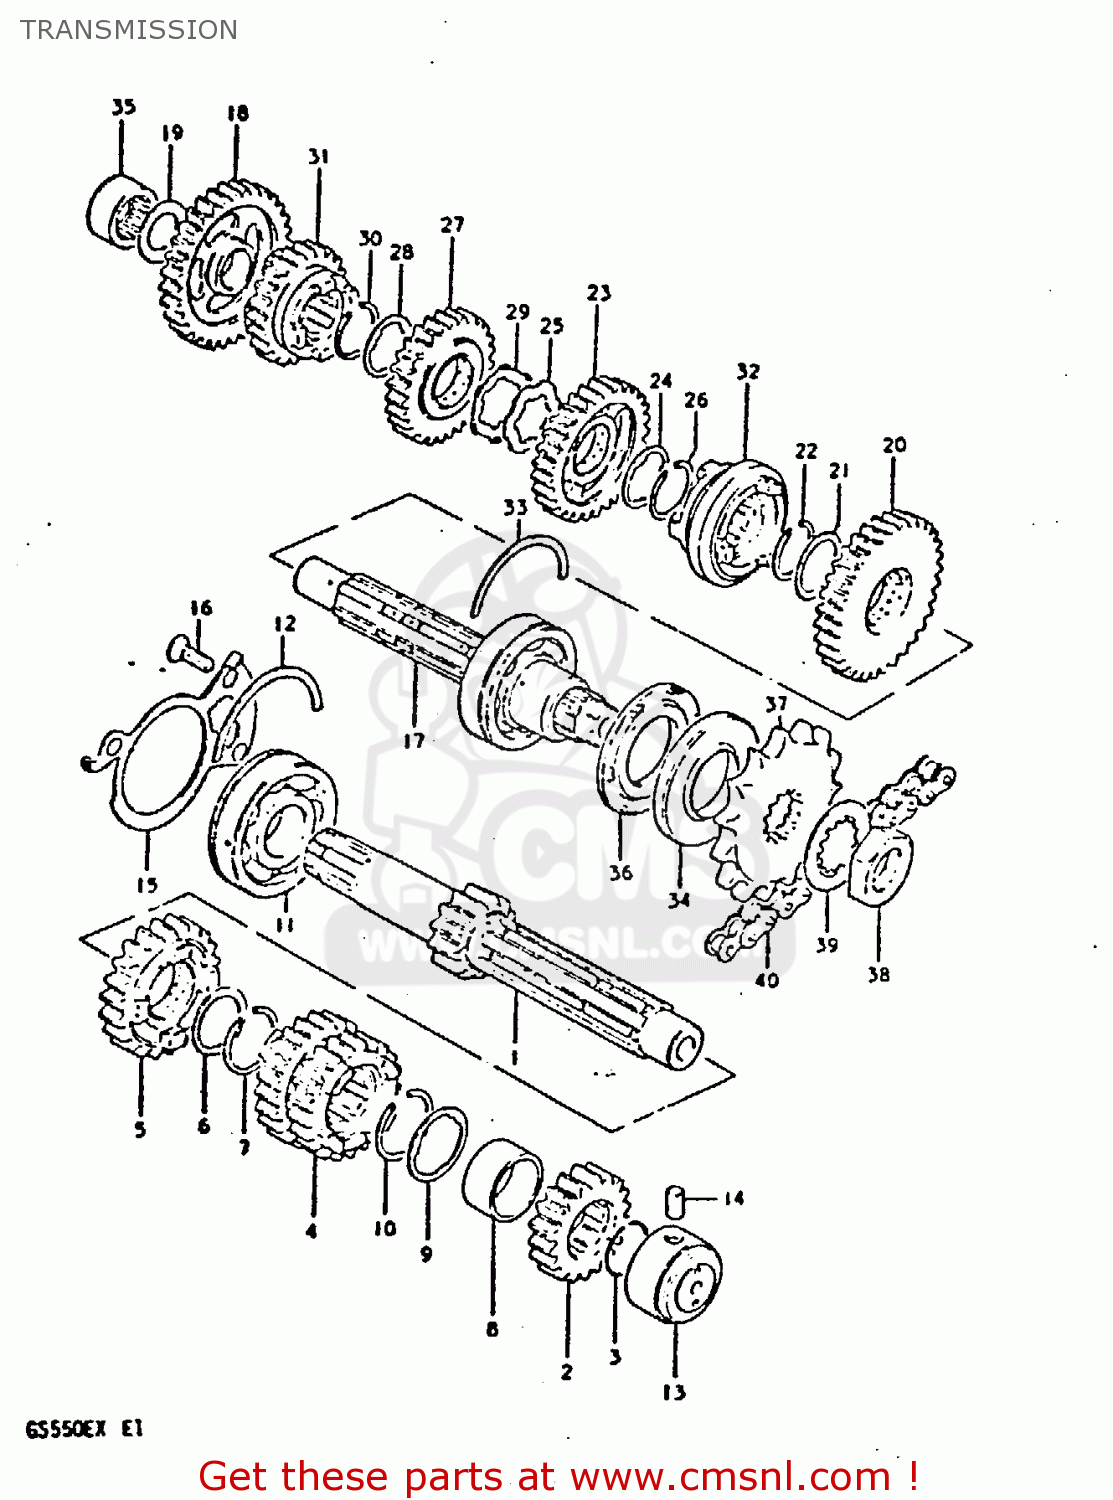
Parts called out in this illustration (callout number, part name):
1	SHAFT,COUNTER
2	GEAR,SECOND DRIVE
3	RING,SNAP
4	GEAR,THIRD DRIVE
5	GEAR,FIFTH DRIVE
6	WASHER
7	CIRCLIP
8	GEAR,SIXTH DRIVE
9	WASHER,LOCK
10	CIRCLIP
11	BEARING(25X62X17)
12	C-RING
13	BEARING
14	PIN
15	PLATE,COUNTERSHAFT BEARING
16	SCREW
17	SHAFT,DRIVE
18	GEAR,FIRST DRIVEN
19	WASHER
20	GEAR,SECOND DRIVEN
21	WASHER
22	CIRCLIP
23	GEAR,THIRD DRIVEN
24	WASHER,LOCK
25	WASHER,LOCK
26	CIRCLIP
27	GEAR,FOURTH DRIVEN
28	WASHER,LOCK
29	WASHER
30	CIRCLIP
31	GEAR,FIFTH DRIVEN
32	GEAR,SIXTH DRIVEN
33	C-RING
34	SEAL,OIL(32X62X7)
35	ROLLER BEARING (20X34X1
36	SEAL,OIL(32X62X5.5)
37	SPROCKET,ENGINE
38	NUT
39	WASHER
40	CHAIN ASSEMBLY,DRIVE
